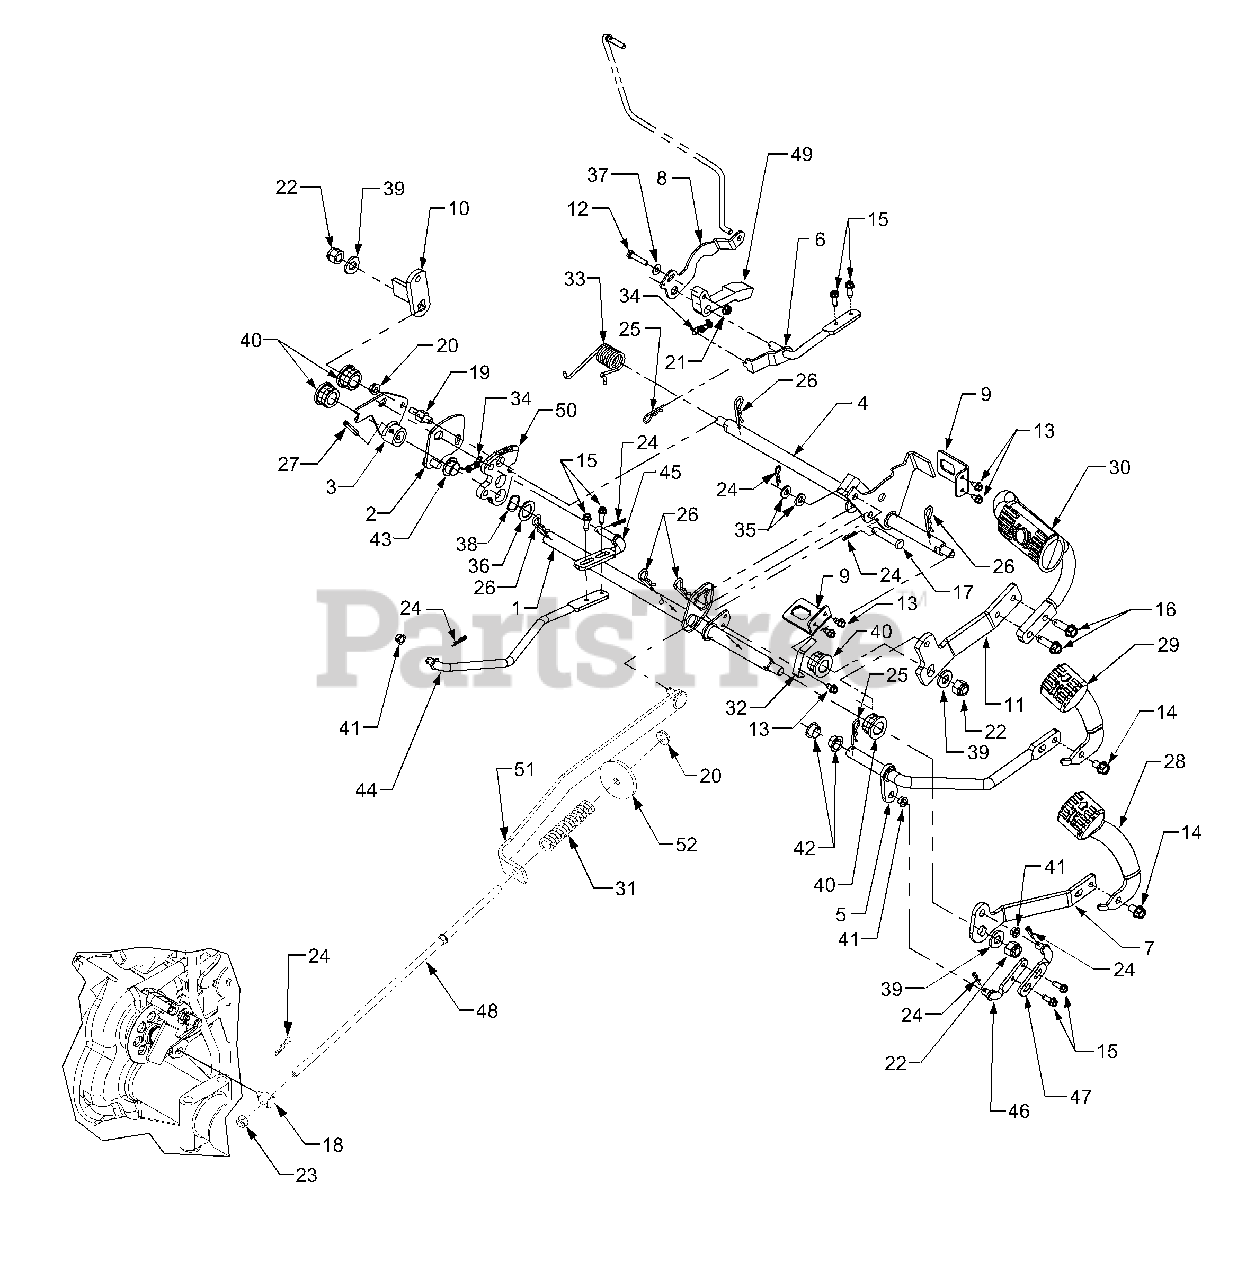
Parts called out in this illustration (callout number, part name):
1	Shaft Assembly, Pedal
2	Plate, Disengagement
4	Shaft Assembly, Brake.
5	Shaft Assembly, Reverse.
6	Rod Assembly, Cruise
7	Link, Pedal Mounting
8	Bracket, Rod Adjust
9	Bracket, Switch
10	Lever, Brake Diff Lock
11	Link, Brake Pedal
12	Screw, Hex Cap, 1/4-20 x 1.25 GR5
13	Screw, Hex Wash. Hd. Tapp 1/4-20 x .5
14	Screw, Hex Wash. Hd. Tapp 3/8-16 x .75
15	Screw, Hex Wash. Hd. Tapp 1/4-20 x .75
16	Screw, Hex Wash. Hd. Tapp 3/8-16 x 1.25
17	Pin, Clevis, 3/8 x 2.015
18	Ferrule, Adjust
19	Stud, Actuator
20	Nut, Hex Flange Lock, 5/16-18
21	Nut, Hex Flange Lock, 1/4-20
22	Nut, Hex Insert Lock, 1/2-20
23	Nut, Hex Insert Lock, 5/16-18
24	Pin, Internal Cotter
25	Pin, Internal Cotter
26	Pin, Internal Cotter
27	Pin, Spiral Spring, .25 x 1.5
28	Pedal, Forward
29	Pedal, Reverse
30	Pedal, Brake
31	Spring, Compression
32	Spring, No Cut Reverse
33	Spring, Torsion
34	Spring, Extension, .380 OD x 1.44
35	Washer, Flat, .344 x .688 x .065
36	Washer, Flat, .79 x 1.24 x .060
37	Washer, Flat, .25 x .62
38	Washer, Wave, .785 x 1.0 x .012
39	Washer, Flat, .531 x 1.06 x .134
40	Bearing, Hex Flange
41	Bearing, Flange
42	Bearing, Flange
43	Bearing, Flange
44	Rod, Rear Control
45	Rod, Front Control
46	Rod, Rear Connecting
47	Rod, Front Connecting
48	Rod, Brake
49	Cruise Latch
50	Plate, Cruise
51	Link Assembly, Brake
52	Washer, Flat, .341 x 2.25 x .10
